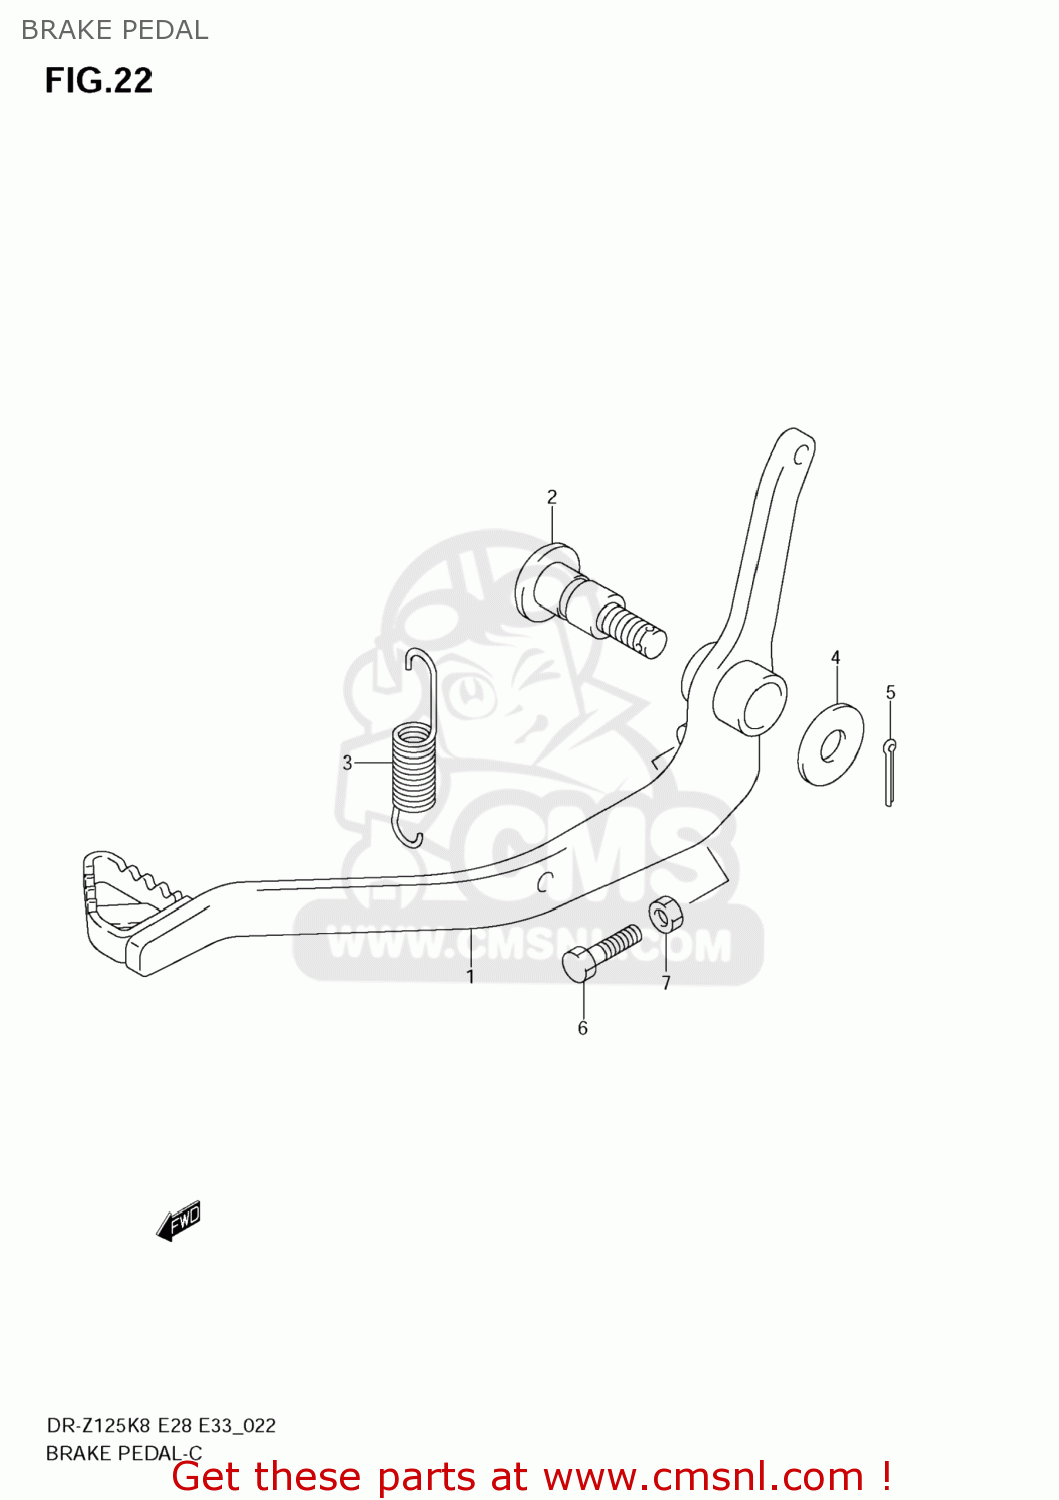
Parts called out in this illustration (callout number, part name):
1	PEDAL,BRAKE
2	SHAFT,BRAKE PEDAL
3	SPRING
4	WASHER
5	PIN
6	BOLT(6X18)
7	NUT
